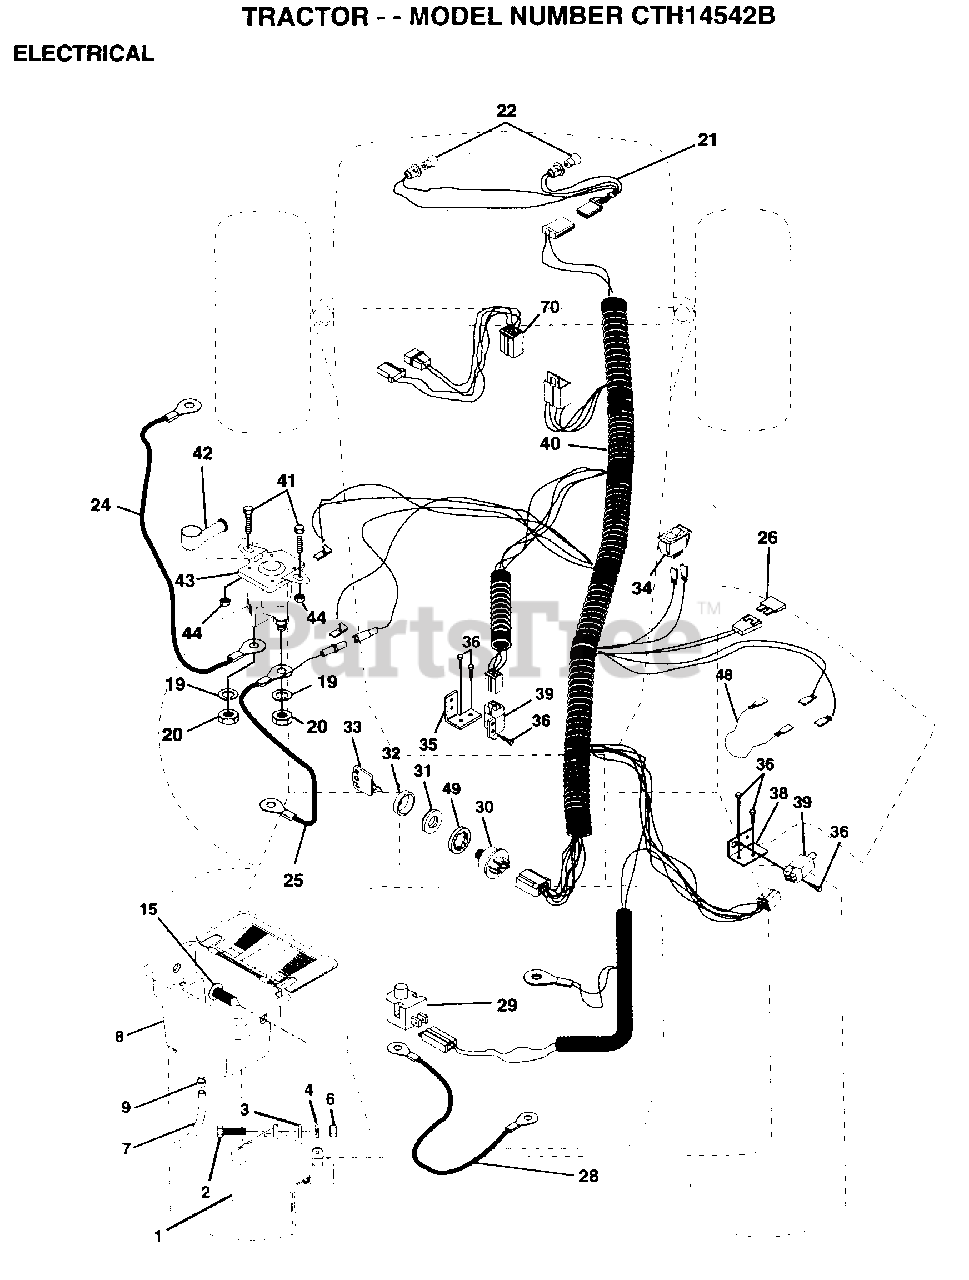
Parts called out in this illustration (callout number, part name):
2	BOLT LT
3	WASHER
4	LOCKWASHER
7	TUBE T
9	HOSE CLAMP T
15	FASTNER.SNAP-IN
20	NUT
21	"HARNESS,LIGHT SOC"
22	HEADLAMP BULB
24	CABLE.BTRY.6GA.RD
25	CABLE.BTRY.6GA.38
26	FUSE HYT
28	CABLE T
29	SWITCH SEAT
32	COVER KEY SWITCH
33	KEY MLD GEN DELTA
34	SWITCH LT
35	BRACKET LT
36	SCREW
38	BRACKET SWITCH IN
39	SWITCH INTERLOCKT
40	HARNESS.IGN.DASH.
41	BOLT HXHD FIN
44	NUT HXKEP 1/4X20
48	ADAPTER AMMETER
49	LOCKWASHER
70	HARNESS.ENG.DUAL
